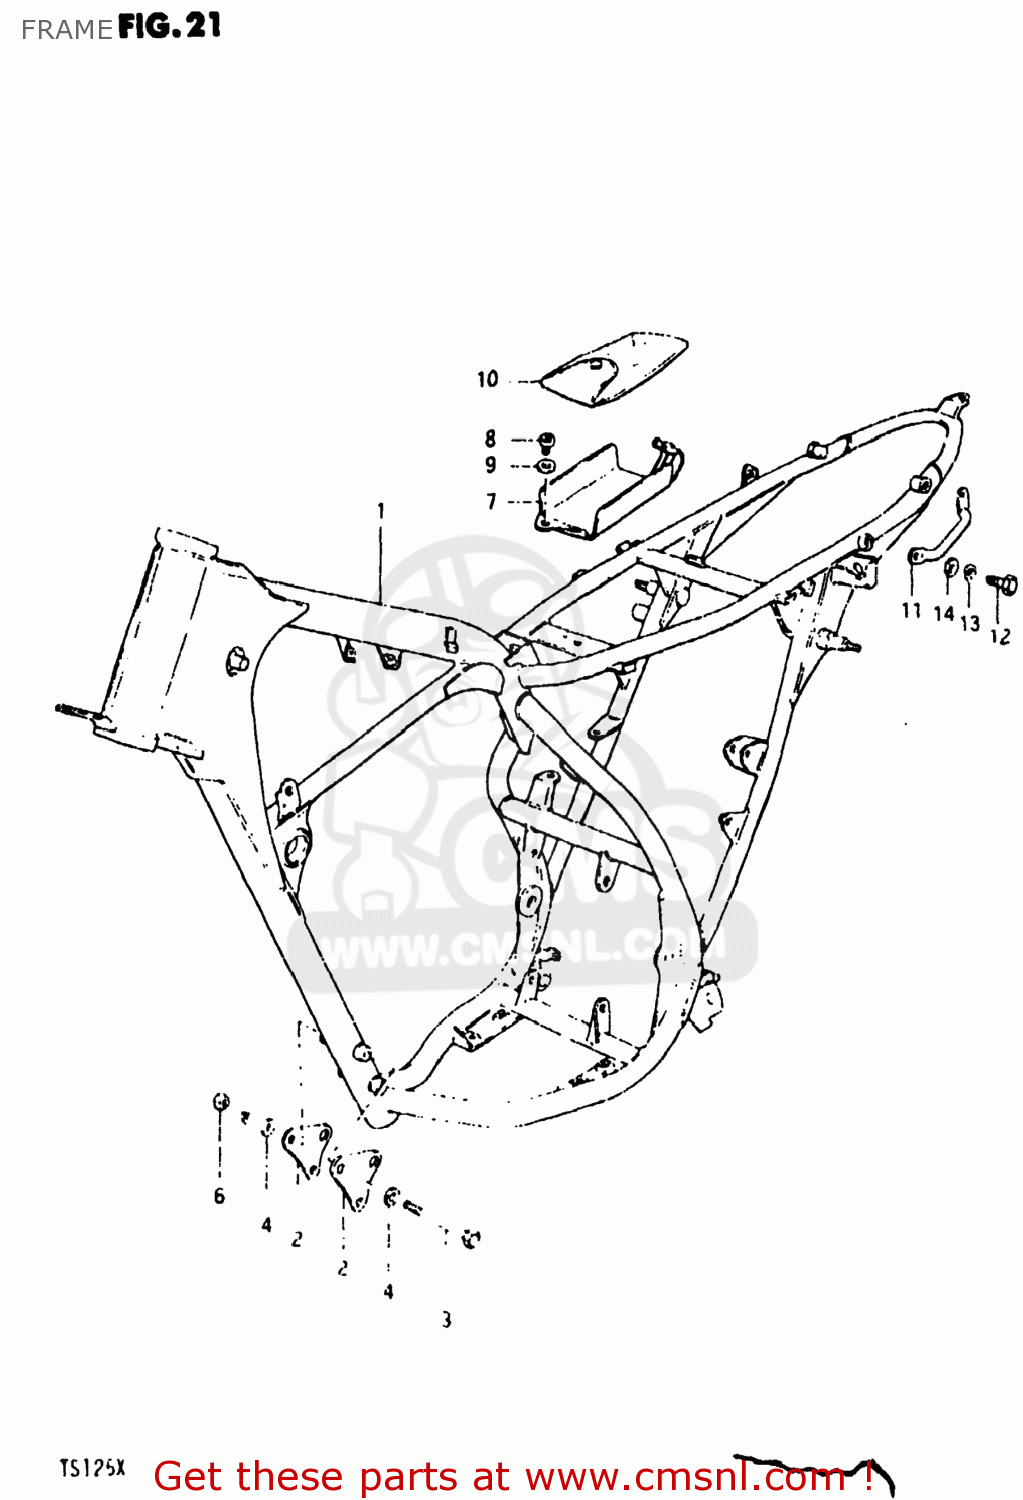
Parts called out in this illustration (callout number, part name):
1	FRAME
2	PLATE,ENG MTG
3	BOLT,8X75
4	WASHER
5	WASHER,LOCK,8.
6	NUT
7	HOLDER,TOOL
8	SCREW
9	WASHER
10	TOOL SET
11	GRIP,FRAME HANDLE
12	BOLT
13	LOCK WASHER
14	WASHER
